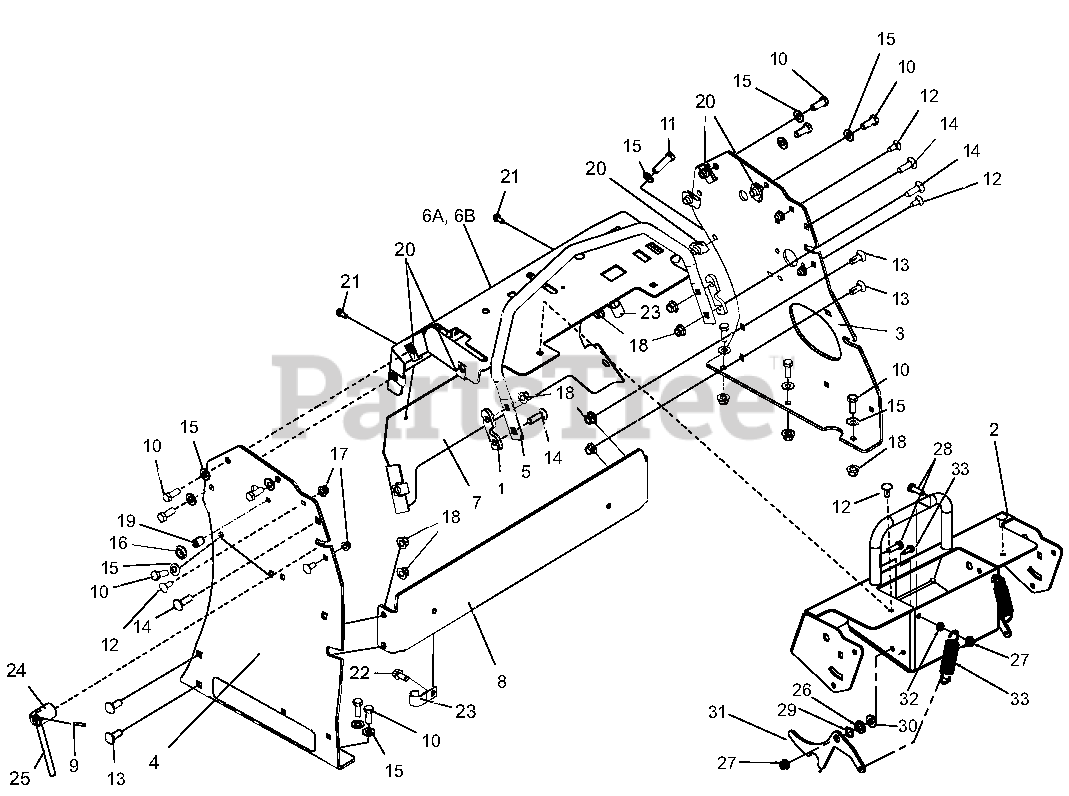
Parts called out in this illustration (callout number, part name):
1	SHIM, 5 DEG SPEED BAR
2	WLDMT, CONTROL PANEL, PRO-STANCE
3A	PANEL, TOWER RH, PRO-STANCE (SN 000101-019999)
3B	PANEL, TOWER RH, PRO-STANCE (SN 020000+)
4A	PANEL, TOWER LH, PRO-STANCE (SN 000101-019999)
4B	PANEL, TOWER LH, PRO-STANCE (SN0 020000+)
5	STOP, FORWARD STEERING
6A	PANEL, CONTROL PRO-STANCE (994111,112,113,114,115)
6B	PANEL, CONTROL PRO-STANCE (994117,118)
7	PLATE, FRONT BACKER
8	STIFFENER, TOWER
9	PIN, SPRING
10	BLT-HEX .38-16 X 1
11	BLT-HEX .38-16 X 1.00 GR5 YWZC
12	BLT-RDHDSQNK .31-18 X .75 G5 YWZC (SN 020000+)
13	BLT-RDHDSQNK .3
14	BLT-RDHDSQNK .3
15	WSHR-FL-STL .406 X .812 X .065 YWZ
16	NUT, 1/2-13 JAM GR5Y
17	NUT-LK-NYL-FLG .31-18 YWZC
18	NUT-LK-NYL-FLG .38-16 YWZC
19	BALL SPRING PLUNGER .500-13
20	NUT, RTNR .375-16 X .37
21	SCR-TAP .25-20 X .50 HWH TR YWZ
22	SCR-TAP .38-16 X .75 HWH TR YWZ
23	P-CLIP, .500 INSULATED
24	BASE, LOCK LEVER Y
25	LEVER, LOCK Y
26	BSH-FLG .312 X .500 X .344 (SN 020000+)
27	NUT-LK-NYL-FLG .31-18 YWZC (SN 020000+)
28	BOLT, HEX .31-18 X 1.00 GR4 YWZC (SN 020000+)
29	WAVE WASHER .531 X .781 X .125 FH (SN 020000+)
30	WASHER-FL-STL .38 X .875 .083 YWZC ( SN 020000+)
31	LATCH, PAD MOUNT (SN 020000+)
32	NUT-LK-CTR-JAM .31-18 YWZC (SN 020000+)
33	SPRING, TENSION .105 X .812 X 3.88 (SN 020000+)
33	SCREW, TAPPING .31-18 .75 HEX WASHER HEAD
